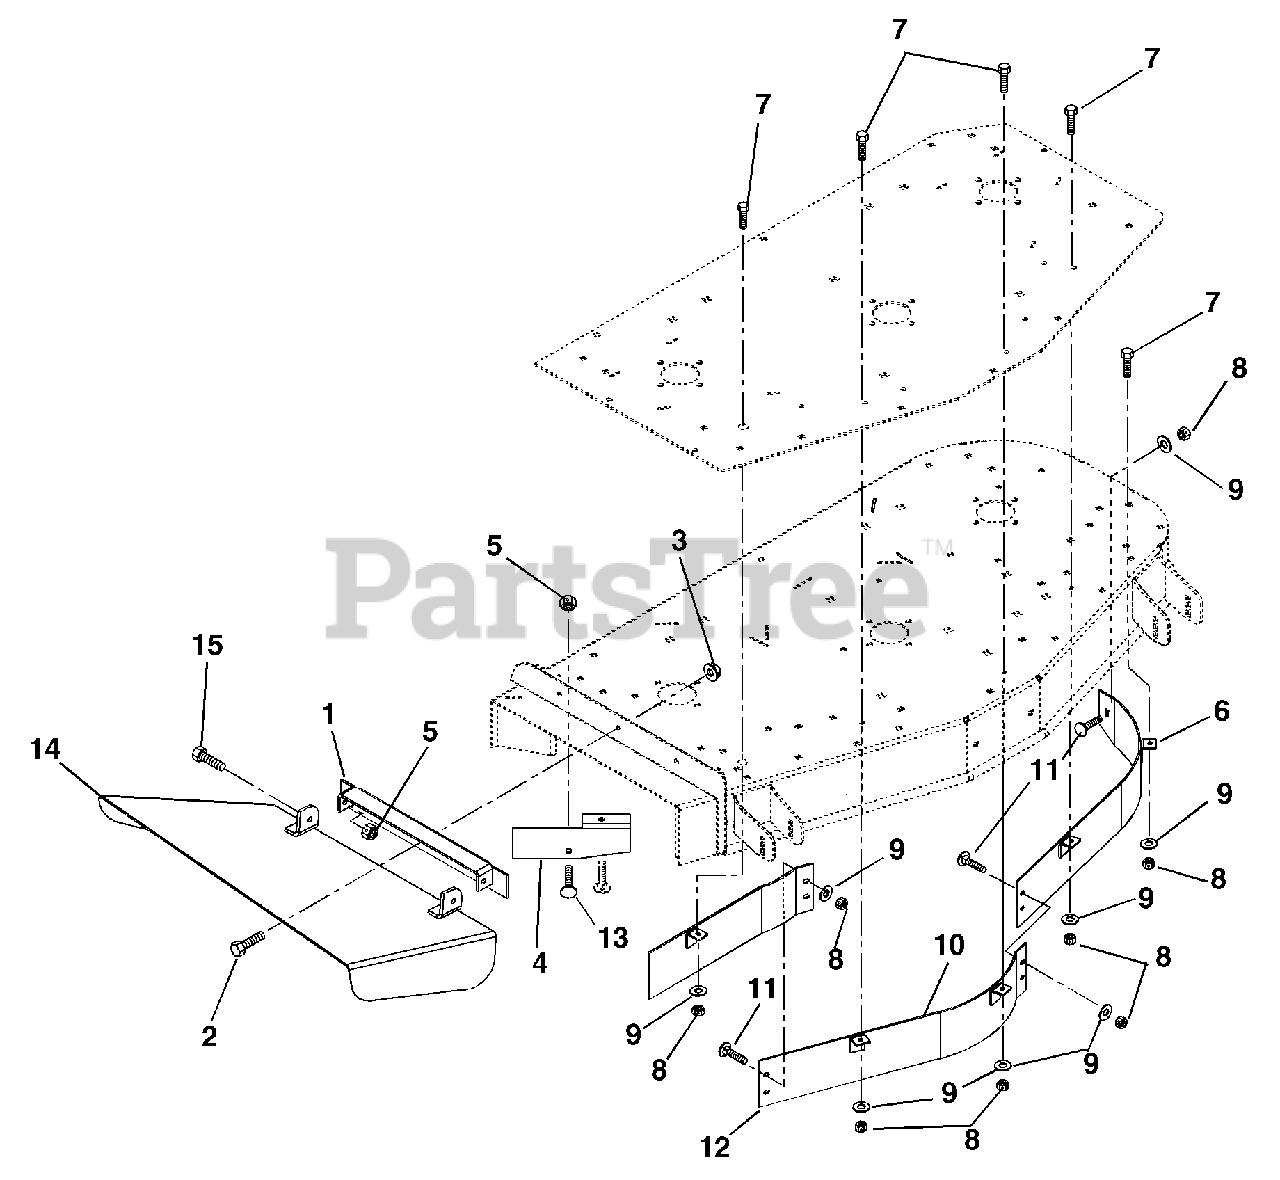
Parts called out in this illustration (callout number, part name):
1	Weldment, Discharge Chute Bracket
2	Bolt-Hex .38-16 x 1.00 Grade 5
3	Nut-Locking-Flange .38-16
4	Deflector 50"
5	Nut-Locking-Center .38-16
6	Weldment, 50" Left Hand Baffle-Upper
7	Bolt-Hex .31-18 x 1.00 Grade 5
8	Nut-Locking-Nylon .31-18
9	Washer-Flat-Steel .312 x .734 x .065
10	Weldment, 50" Center Baffle-Up
11	Bolt-Round Head Square Neck .31-18 x .75 Grade 5
12	Weldment, 50" Right Hand Baffle-Upper
13	Bolt-Round Head Square Neck .38-16 x 1.00 Grade 2
14	Weldment, Discharge Chute 50"
15	Bolt-Hex .38-16 x 1.00 Grade 5
16	50" Discharge Cover
17	50" Mulch Kit
